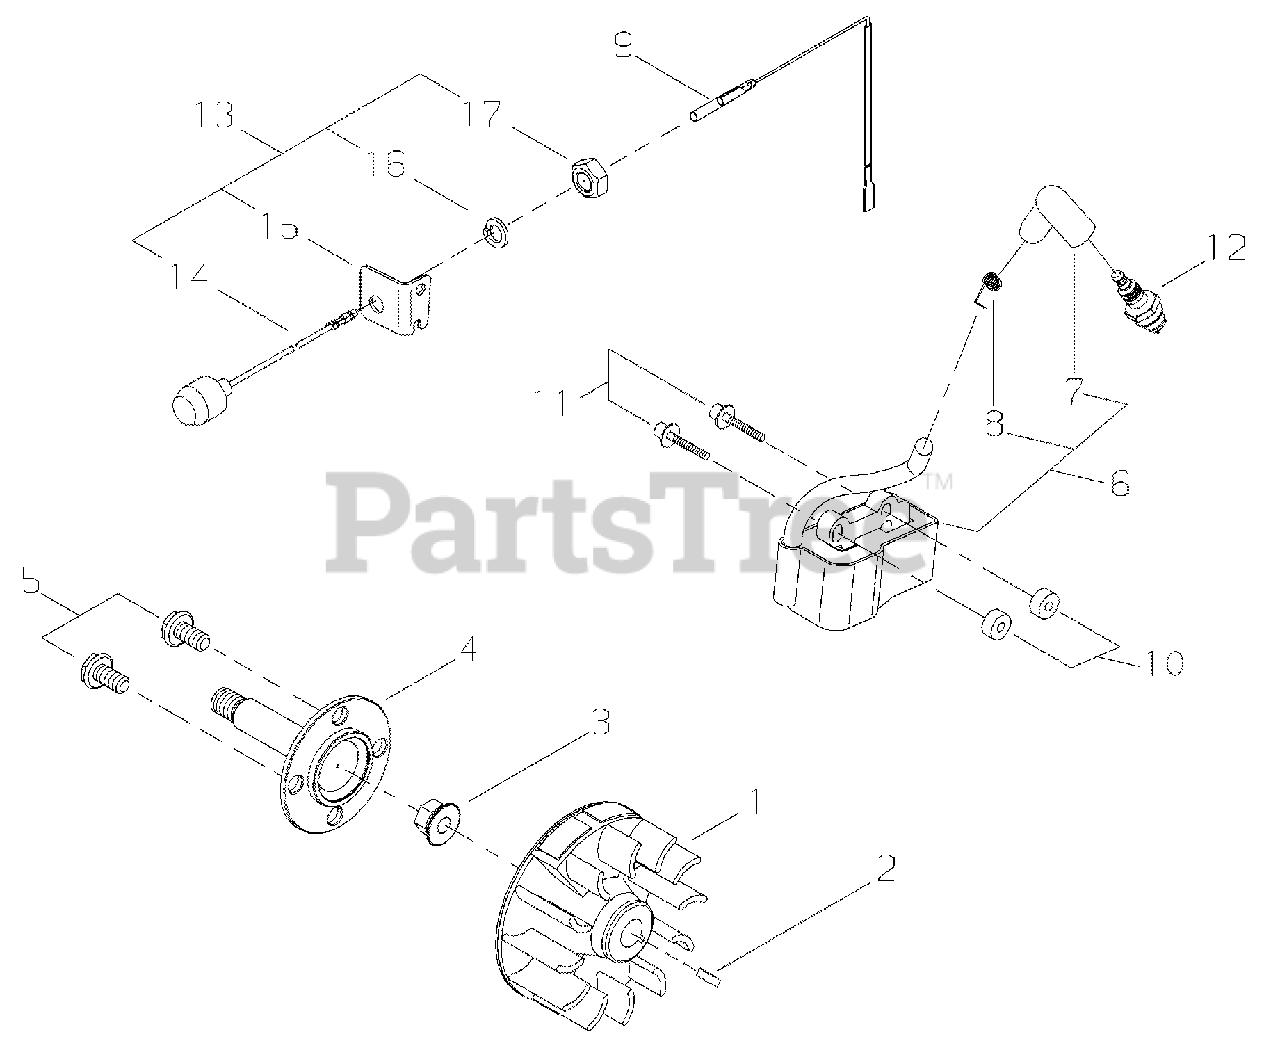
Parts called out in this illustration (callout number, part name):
1	FLYWHEEL
2	KEY - 3X10
3	NUT - 8
4	SHAFT, PUMP
5	BOLT - FLANGE
6	IGNITION COIL ASSY
7	CAP, SPARK PLUG
8	TERMINAL, SPARK PLUG CAP
9	LEAD - IGNITION
10	INSULATOR
11	SCREW - 4X26
12	SPARK PLUG -- CMR-5H
13	IGNITION SWITCH ASSY
14	SWITCH, IGNITION
15	BRACKET
16	LOCKWASHER
17	NUT
